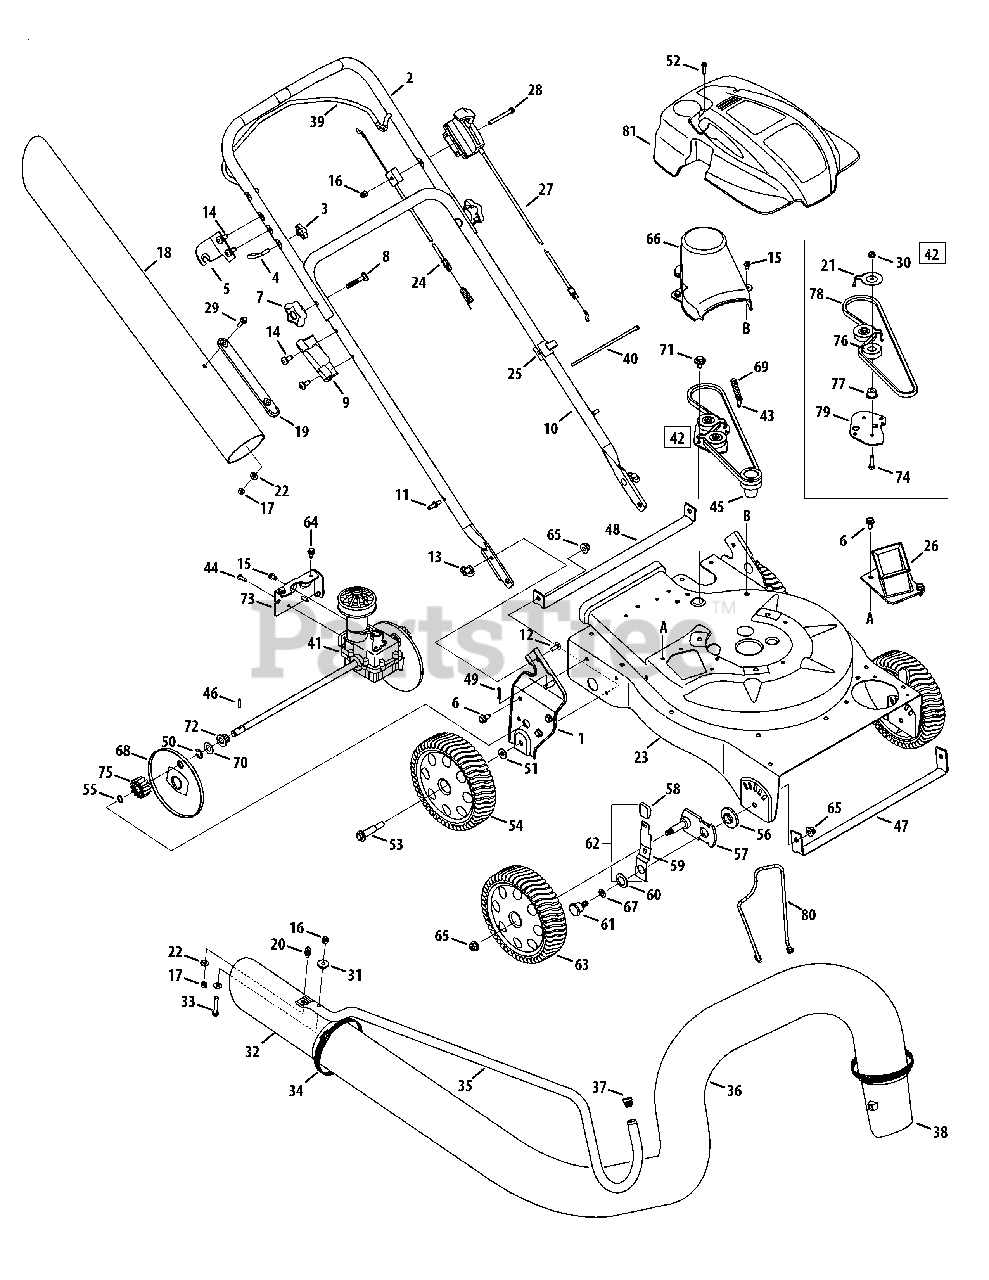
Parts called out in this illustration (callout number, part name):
1	Handle Bracket Ass’y RH
2	Upper Handle
5	Upper Handle Bracket
6	Hex Cap Screw, 5/16-12 x.750
7	Handle Knob, 5/16-18
8	Carriage Bolt
9	Nozzle Handle Clip
12	Carriage Screw, 1/4-20 x.75
13	Wing Nut, 1/4-20
14	TT Screw, 5/16-18 x .750
15	Screw, 1/4-20 x .500
16	Cap Lock Nut, 1/4-20
17	Hex Lock Nut, 1/4-20
18	Hose Extension
19	Chute Strap
21	Belt Keeper
22	Flat Washer.271 ID x.630 OD
23	Upper Flail Housing
24	Drive Control Cable
25	Cable Guide
26	Chipper Chute Assembly
27	Speed Control Cable
28	Hex Screw, 1/4-20 x 2.50
29	Screw, 1/4-20 x .75
30	Flange Lock Nut, 1/4-20
32	Hose Nozzle
33	Hex Cap Screw, 1/4-20 x 2.625
34	Adjustment Clamp
36	Vacuum Hose
37	Handle Plug
38	Hose Adapter
39	Drive Control
40	Cable Tie
41	Transmission Assembly
42	Idler Assembly (Incl. Ref.# 76-79)
43	Shoulder Screw, #12-24 x .30 x .46
44	Screw, #12-16 x .750
45	Impeller Hub
46	Dowel Pin
47	Front Wheel Support Brace
48	Rear Wheel Support Brace
49	Cotter Pin
51	Flat Washer, .406 x .875 x .105
52	Screw, #12-16 x 1.00
53	Shoulder Screw, 3/8-16
54	Wheel, 8 x 2.125
55	Snap Ring
56	Height Adjustment Bearing
57	Pivot Arm Assembly
58	Height Adjustment Knob
59	Spring Lever
60	Bell Washer, .760 ID x.25 OD
61	Shoulder Screw, .750 x.500
62	Height Lever Assembly (Incl. Ref.# 58-59)
63	Wheel 8 x 2
64	Screw, 1/4-20 x .625
65	Flange Lock Nut, 3/8-16
66	Belt Cover
67	Thrust Washer, .375 ID x.70 OD
68	Wheel Cover
69	Extension Spring, .375 x 2.95
70	Flat Wash, .508ID x1.00OD x.020
71	Shoulder Screw, .560 x.165
72	Drive Axle Bushing
73	Transmission Mounting Bracket
74	Screw, 1/4-20 x 1.00
75	Spur Gear - RH
76	Ball Bearing
77	Flange Spacer,.260 x.659 x.517
78	Belt, 3/8 x 32.5
79	Idler Bracket
80	Tube Holder
81	Engine Shroud
